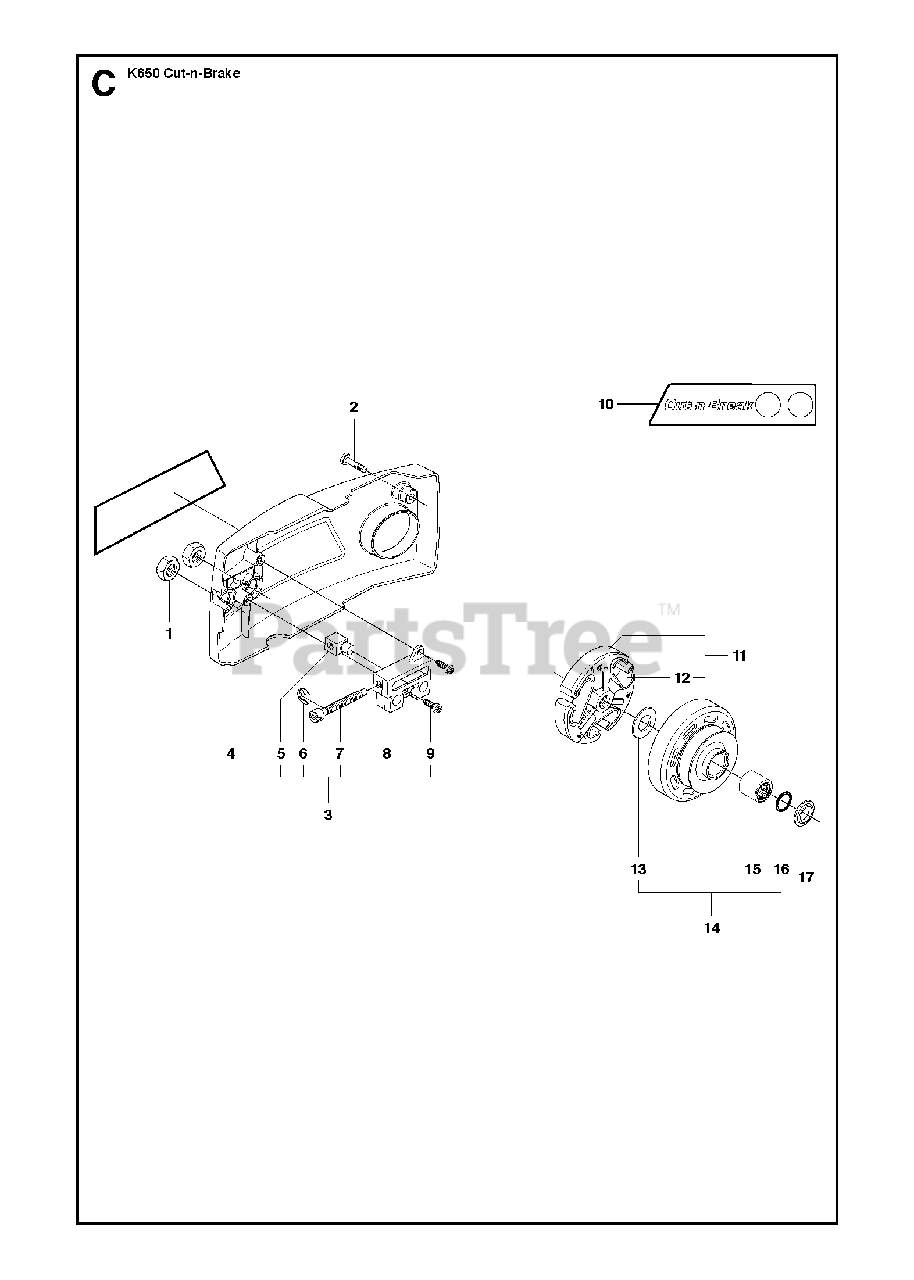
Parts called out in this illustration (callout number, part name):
1	HEXAGON NUT
2	SCREW CCRPANMO
3	CLUTCH COVERIncl. 4 - 9
9	SCREW CRPANT
11	CLUTCH ASSYIncl. 12
12	CLUTCH SPRING
14	NEEDLE BEARINGIncl. 13, 15, 16
